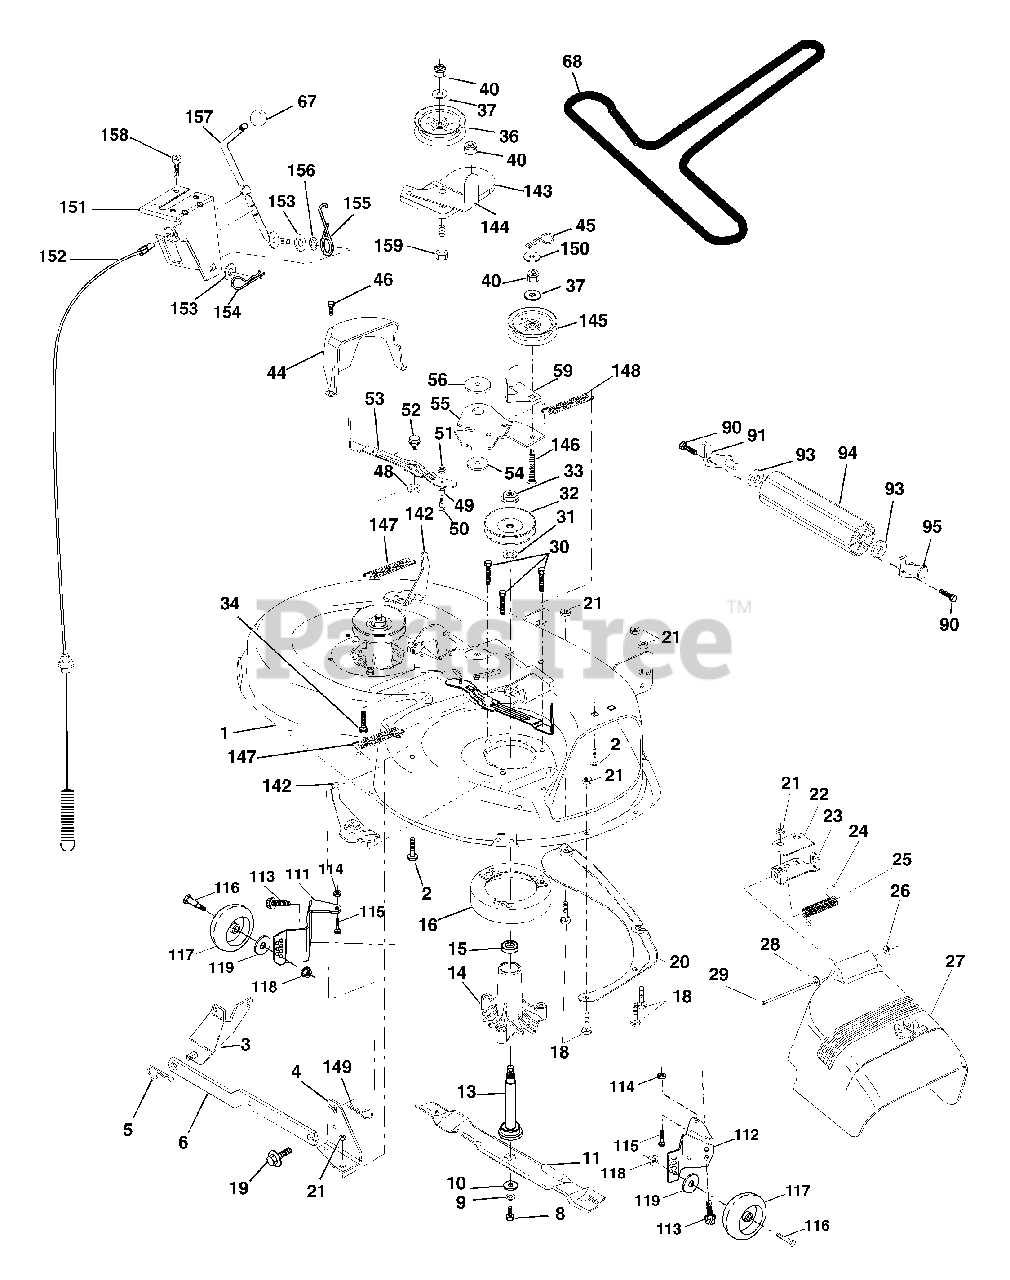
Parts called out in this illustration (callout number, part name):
1	Mower Deck Assembly, 42"
2	Bolt
3	Bracket Asm Fr. Sway Bar 3/42
4	Bracket Asm Deck 42" Sway Bar
5	Retainer Spring
6	Arm, Suspension, Rear
8	Bolt 3/8-24 x 25 Grade 8 patched
9	Washer, Lock
10	Washer, Hardened
11	Blade
13	Shaft Assembly, Mandrel, Vented
14	Housing, Mandrel, Vented
15	Bearing, Ball, Mandrel
16	Stripper, Mower Deck
18	Bolt, Carriage 5/16-18 x 5/8
19	Bolt, Shoulder
20	Baffle, Vortex
21	Nut
22	Stiffener Bracket
23	Bracket, Deflector Mower 42"
24	Cap, Sleeve 80 x 112 Blk Mower
25	Spring, Torsion, Deflector 2 52
26	Nut, Push Phos & Oil
27	Shield, Deflector 42" Blk
28	Washer 11/32 x 5/8 x 16 Gauge
29	Rod, Hinge 42" 6 75 W/G
30	Screw Thdrol Washer Head
31	Washer, Spacer Mower Vented
32	Pulley, Mandrel
33	Nut, Toplock
34	Bolt
36	Pulley, Idler, Flat
37	Washer 13/32 x 13/16 x 16 Gauge
40	Nut
44	Guard, Mandrel, LH
45	Retainer
46	Screw, Thdrol 1/4-20 x 5/8 T
48	Washer, Hardened
49	Roller Assembly, Cam Follower
50	Bolt, Shoulder #10-24 Grade 5
51	Locknut
52	Bolt, Shoulder 5/16-18 UNC
53	Arm Assembly, Pad, Brake
54	Washer, Hardened
55	Arm, Idler
56	Spacer, Retainer
59	Guard TUV Idler
67	Knob
68	V-Belt, 42" Mower
90	Screw 3/8-16 x 3/4
91	Bracket Asm Noseroller Lh
93	Washer 17/32 x 7/8 x 16 Ga.
94	Roller Nose 38-50"
95	Bracket Asm. Noseroller Rh
111	Bracket Gauge Wheel Lh
112	Bracket Gauge Wheel Rh
113	Screw 5/16-18 x 1/2
114	Nut Keps 5/16-18unc
115	Bolt Carr. 5/16-18 x 5/8
116	Bolt Shld
117	Wheel Gauge Blk
118	Nut Centerlock 3/8-16unc
119	Washer 3/8 x 7/8 x 14 Ga.
142	Arm Spring Brake Mower
143	Bracket Arm Idler 42"
144	Keeper Belt 42" Clutch Cable
145	Pulley Idler Flat
146	Bolt Carriage Idler
147	Spring Extension
148	Spring Return Idler
149	Retainer Spring Yellow
150	Washer 9/32 x 3/4 x 16 Ga.
151	Bracket Clutch Cable
152	Clutch Cable 42"
153	Washer Flat 3/8" Type B
154	Spring Retainer
155	Spring Retention LVR CLTCH CAB
156	Spacer Clutch Cable
157	Rod Clutch Cable 3/8"
158	Screw Hex Thd Cut 1/4-20 x 5/8
159	Bolt Rdhd Sqn 3/8-16 UNC x 1-3/4
